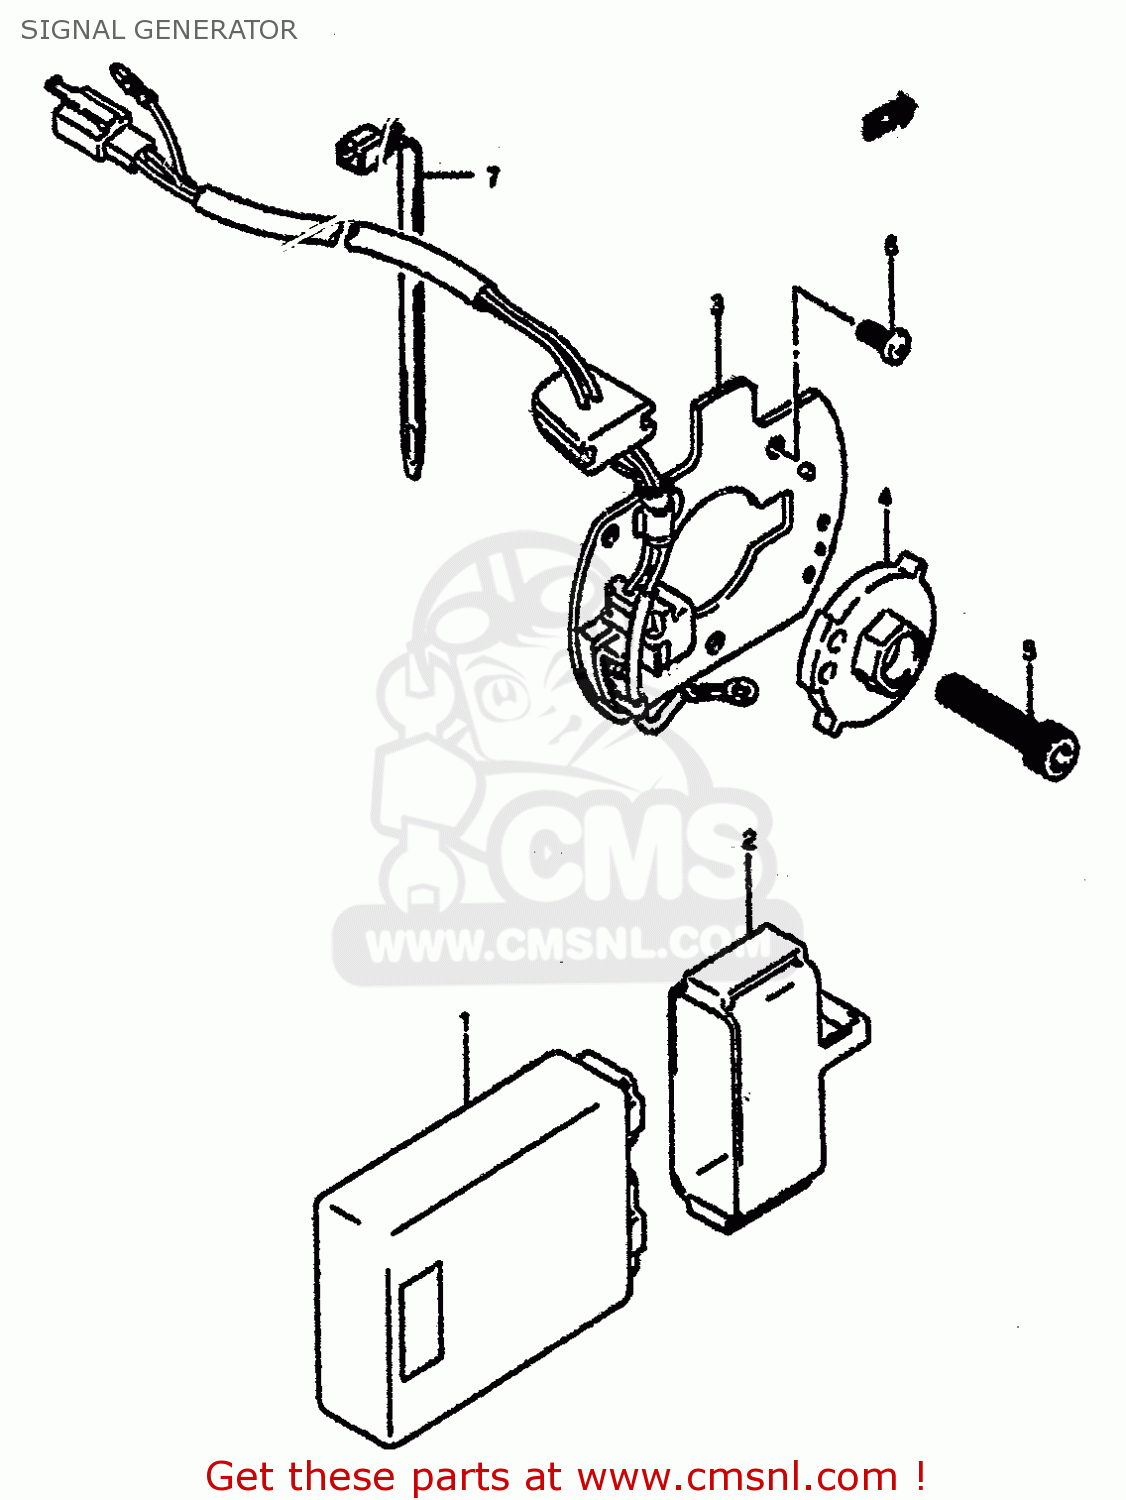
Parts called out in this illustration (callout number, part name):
1	IGNITER
2	CUSHION,IGNITER
3	GENERATOR ASSY,SIGNAL
4	ROTOR,SIGNAL
5	BOLT
6	SCREW
7	CLAMP(L:125)
